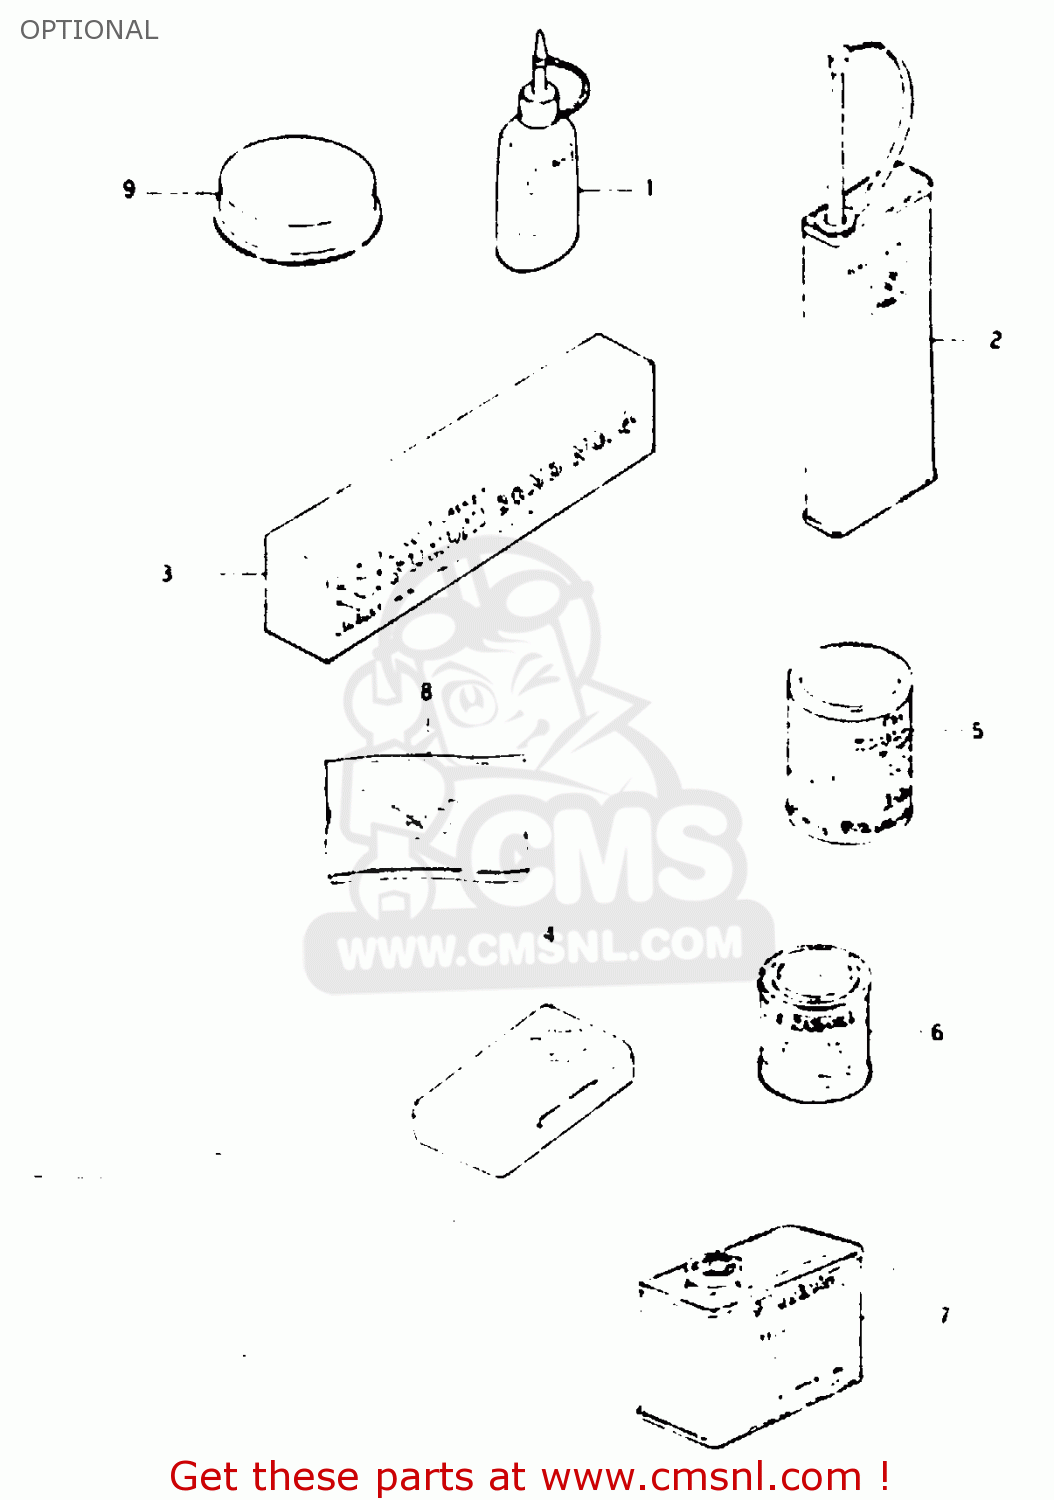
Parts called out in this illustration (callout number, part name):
1	THREAD LOCK NO
2	THREAD LOCK NO.1401 CLEAR 200G
3	BOND 1104
4	TUBE REPARING TOOL
5	GREASE(C)EP2 LITHIUM 150G
6	PAINT,BLACK
7	PAINT (BLACK)
8	ANTI-LEAK ADDITIVE
9	GREASE,PBC FOR BRK PAD 20G
